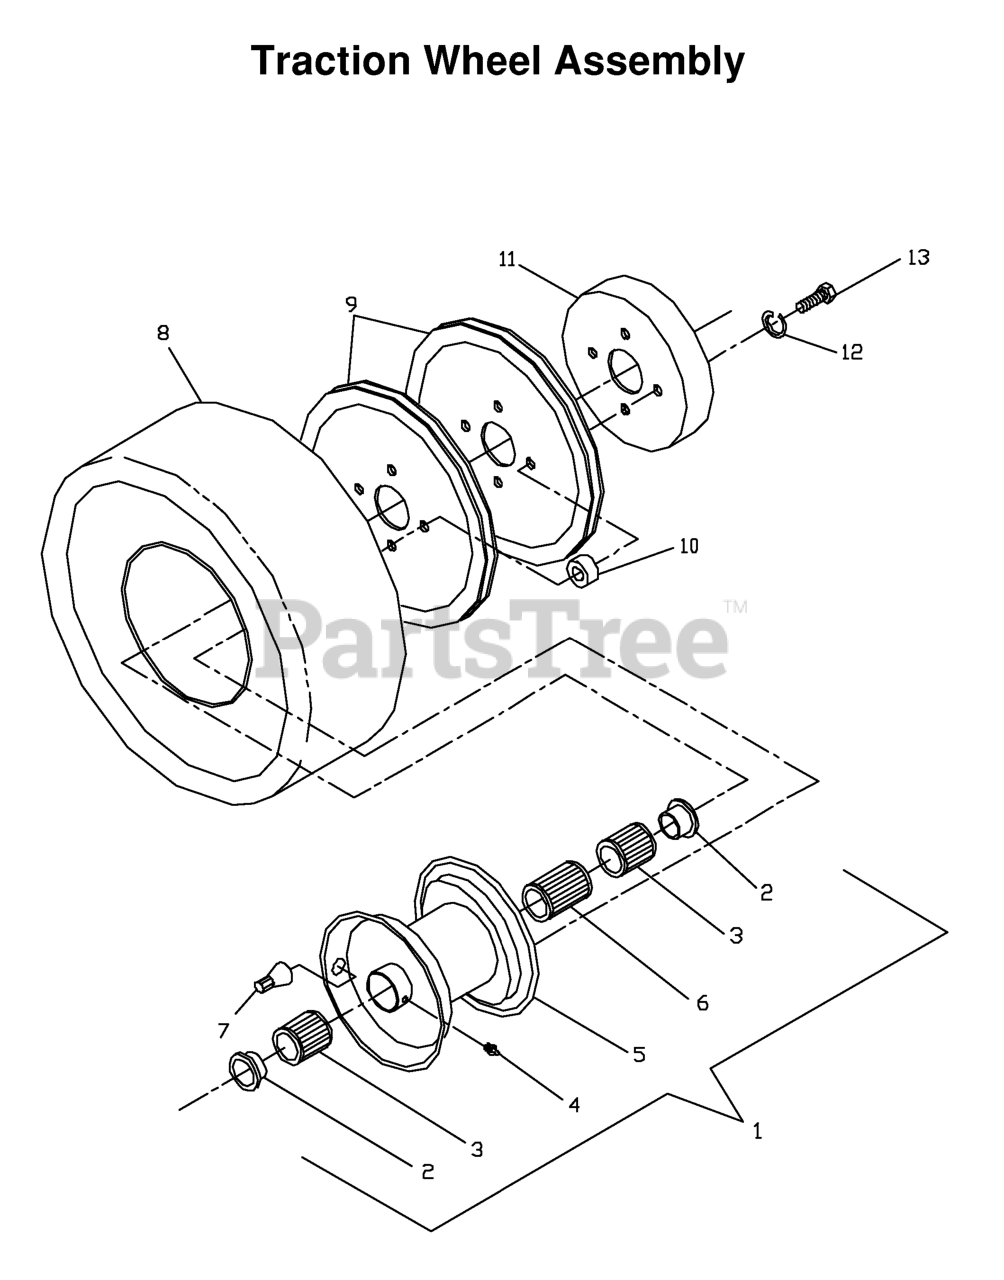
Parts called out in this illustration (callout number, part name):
1	WHEEL.ASM.13X6.5-6.SILVER.COMM
2	BEARING FLANGE
3	ROLLER BEARING (SHORT)
4	ZERK
5	RIM
6	ROLLER BEARING (LONG)
7	VALVE STEM TR-412
8	TIRE
9	TRACTION PULLEY
11	BRAKE DRUM
12	SLW 3/8 STD
13	HCS 3/8F X 1 1/2
